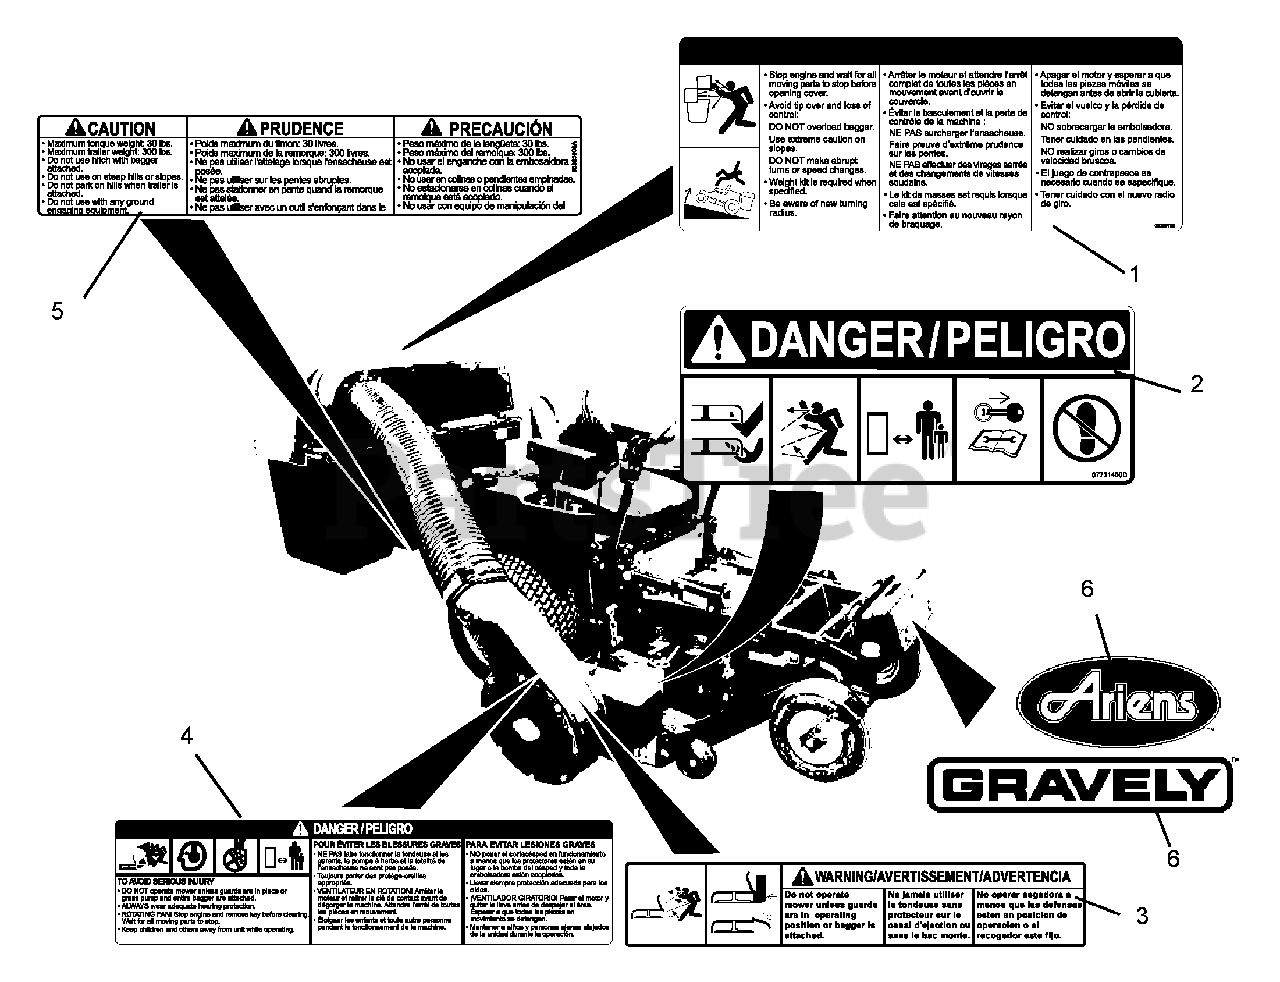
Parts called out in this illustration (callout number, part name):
1	Bagger Cover Decal
2	Mower Pan Danger Decal
3	Warning Decal
4	Grass Pump Caution Decal
5	Decal, Trailer Hitch
6	Decal, Gravely
